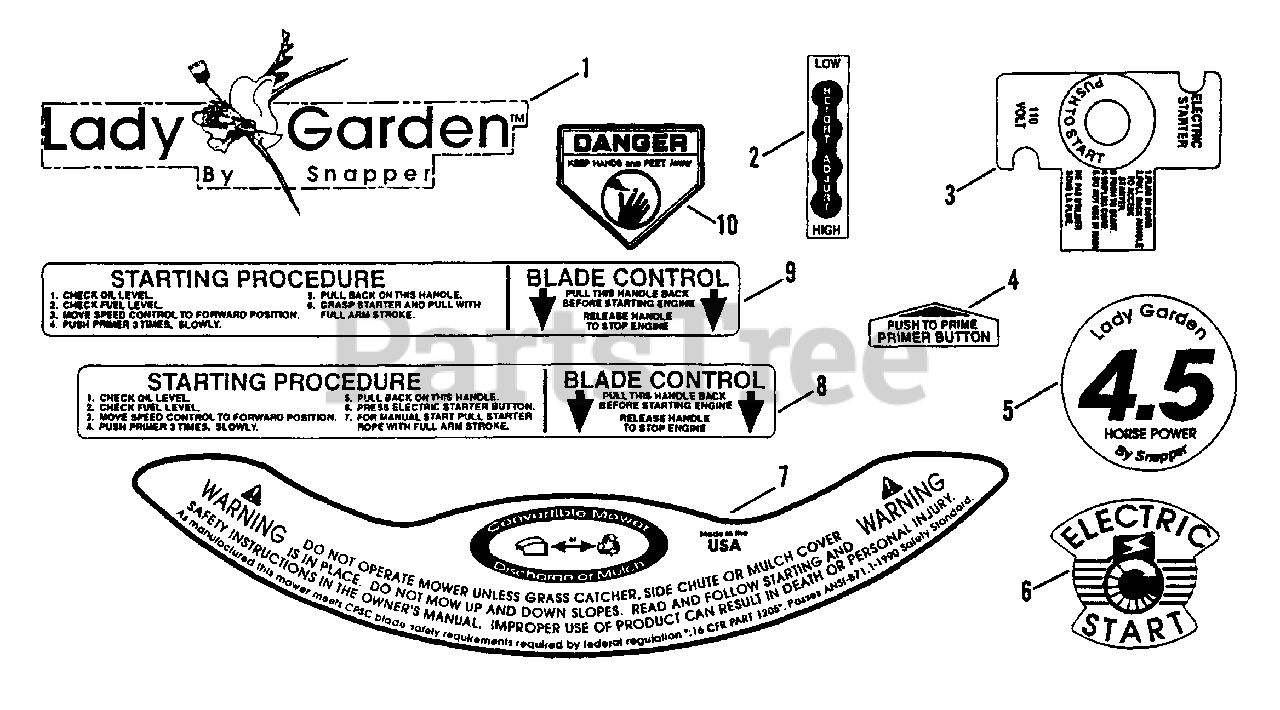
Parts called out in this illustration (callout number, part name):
1	DECAL, Lady Garden
2	DECAL, Height Adjustment
3	DECAL, Electric Starter
4	DECAL, Primer Button (Engine)
5	DECAL, 4.5 Horsepower
6	DECAL, Electric Start
7	DECAL, Chute & Adapter
8	DECAL, Blade Control
9	DECAL, Blade Control
10	DECAL, DANGER
